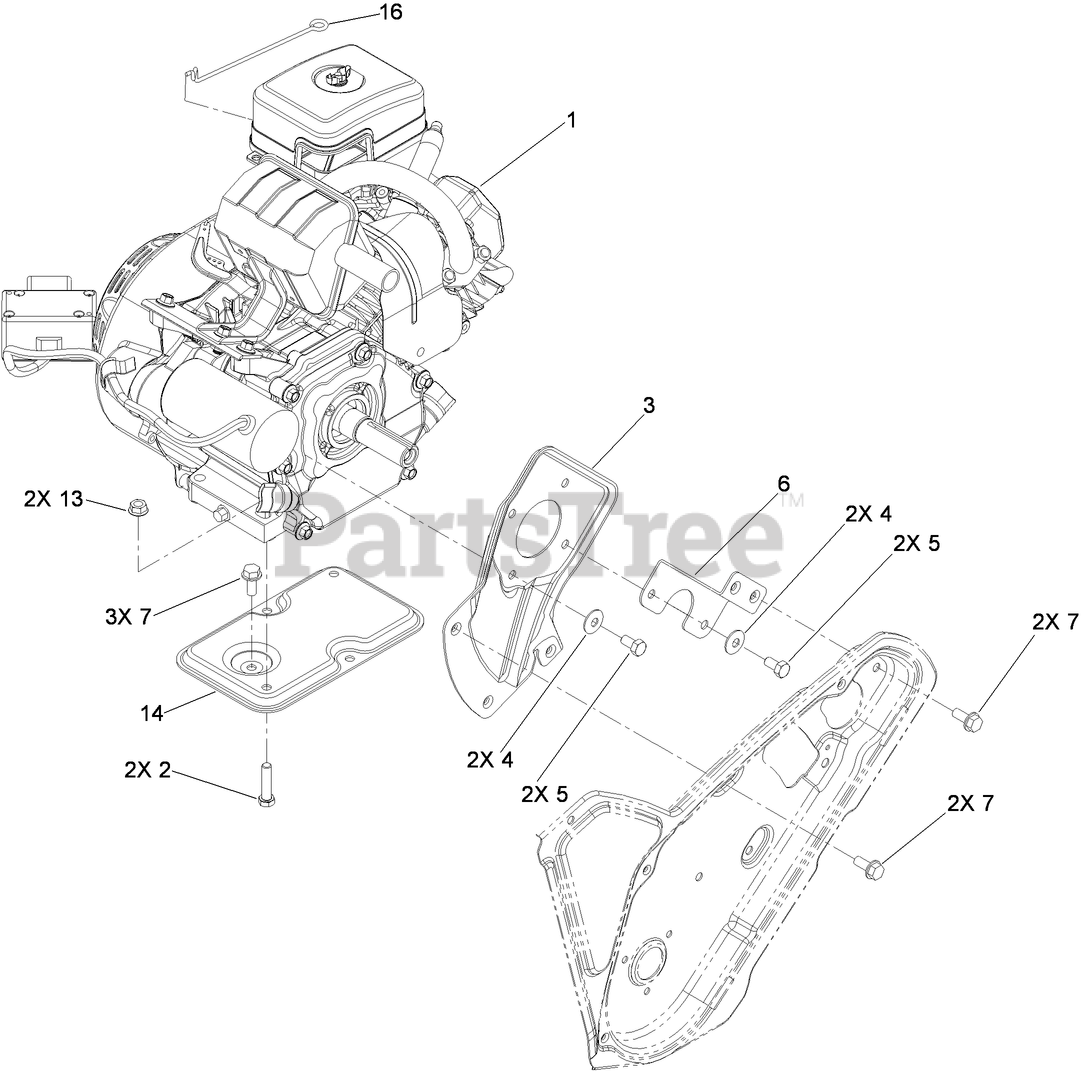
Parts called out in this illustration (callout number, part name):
1	ENGINE-168FDS-1
2	SCREW-HH
3	PLATE-ENGINE, PTO
4	WASHER-BELLEVILLE
5	SCREW-HHF
6	SUPPORT-ENGINE, SIDE
7	SCREW-THD ROLL, HWH
13	NUT-HF
14	SUPPORT-ENGINE
